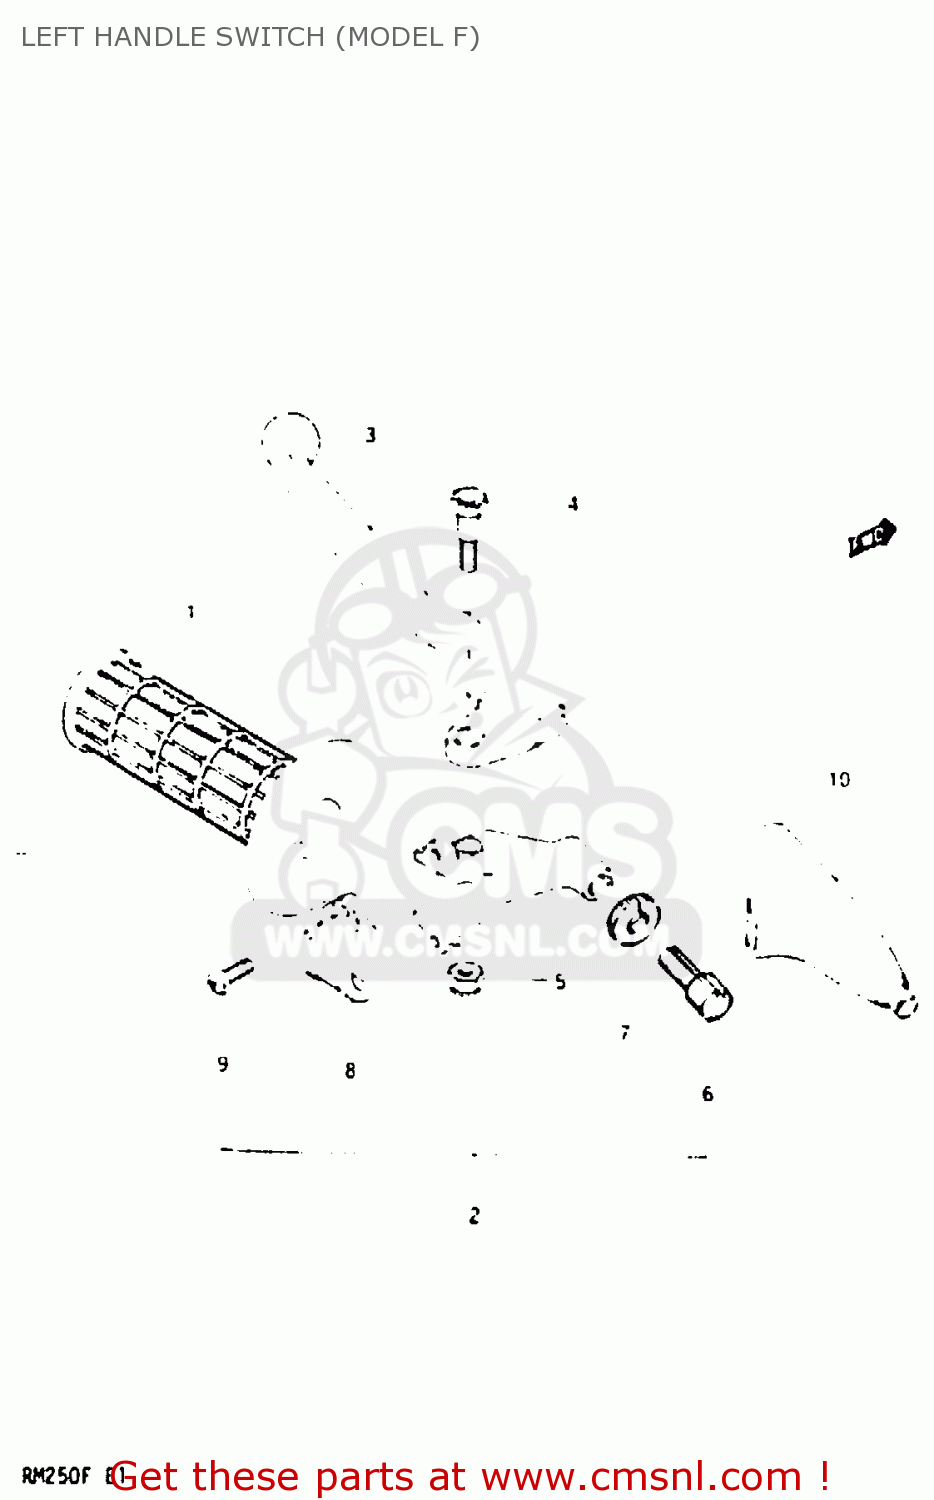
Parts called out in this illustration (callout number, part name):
1	GRIP,LEFT
2	LEVER ASSEMBLY
3	LEVER,CLUTCH
4	BOLT,LEVER
5	NUT
6	ADJUSTER,CABLE
7	NUT,CABLE ADJUSTER LOCK
8	HOLDER,LEVER
9	SCREW (5X14)
10	COVER,CLUTCH LEVER
